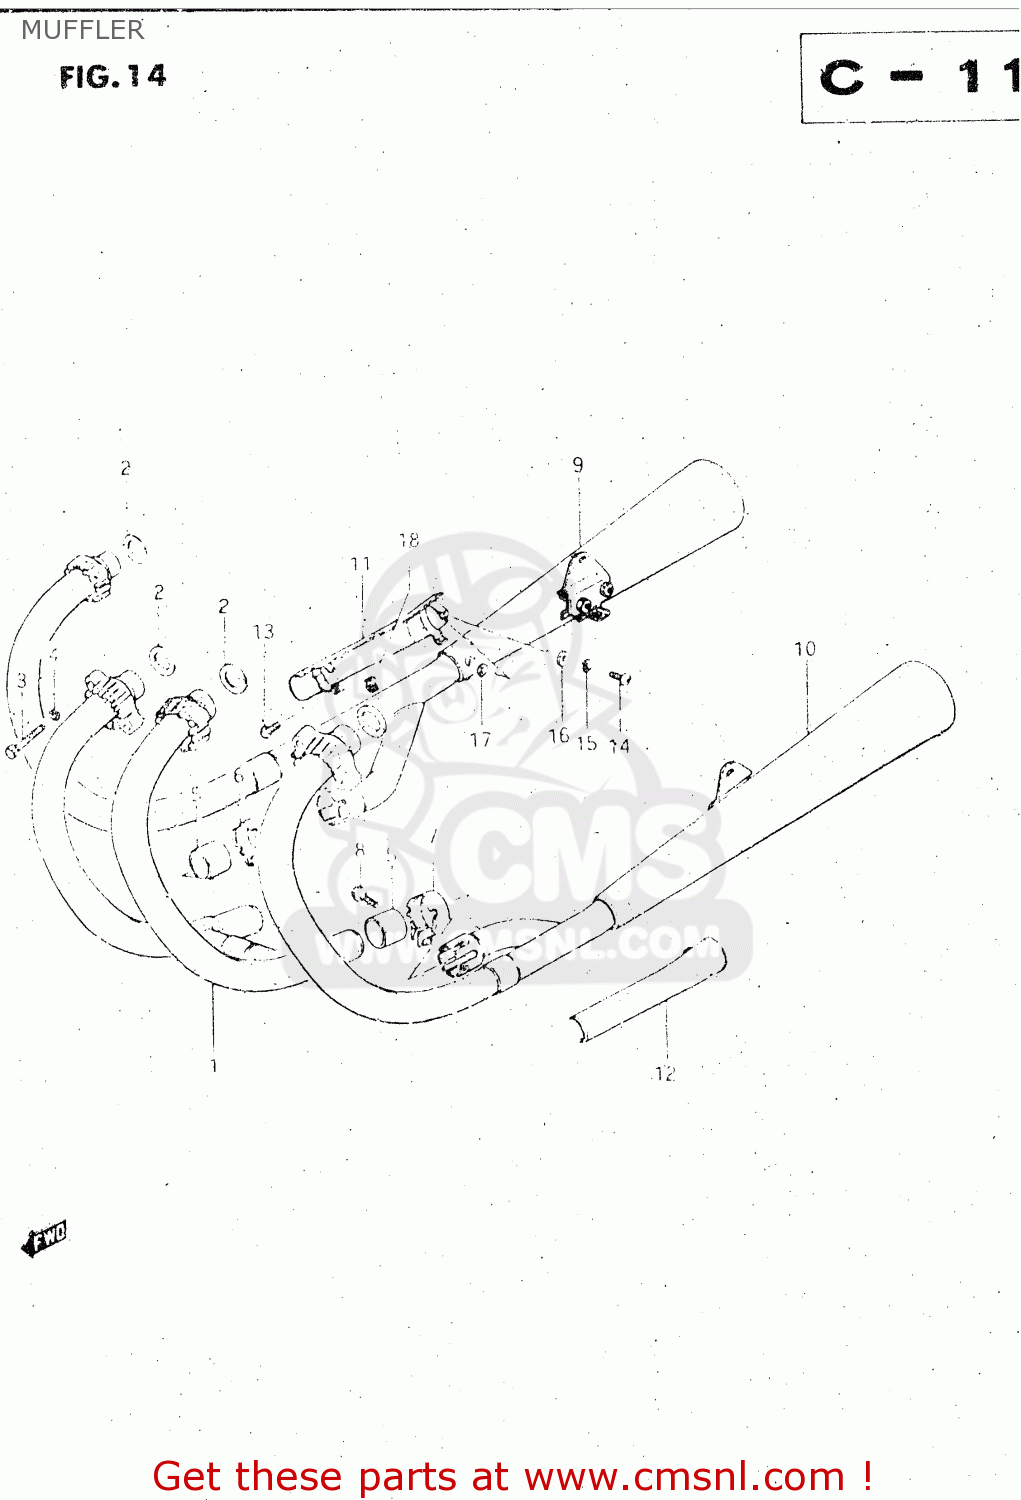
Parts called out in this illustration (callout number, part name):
1	PIPE,EXHAUST,CENTER
2	GASKET,EXHAUST PIPE (NAS)
3	BOLT
4	LOCK WASHER
5	CONNECTOR,MUFFLER
6	CLAMP,MUFFLER CONNECTOR,R
7	CLAMP,MUFFLER CONNECTOR,L
8	BOLT
9	MUFFLER ASSEMBLY
10	MUFFLER ASSEMBLY
11	COVER,MUFFLER,RIGHT
12	COVER,MUFFLER,LEFT
13	SCREW 6X12
14	SCREW 5X20
15	LOCK WASHER
16	WASHER
17	GASKET 6.2X12X1.5 (MCA)
18	CLAMP,MUFFLER COVER
